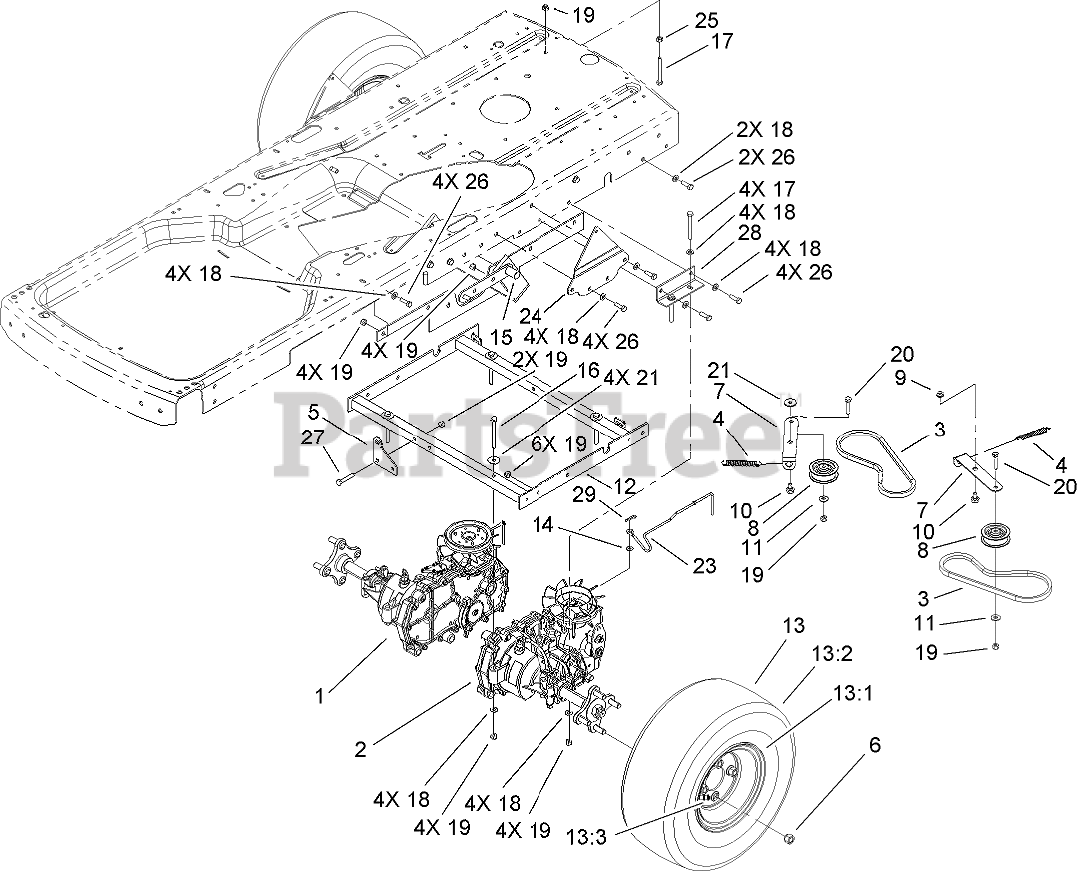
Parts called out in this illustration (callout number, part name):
1	TRANSAXLE-HYDRO, RH
2	TRANSAXLE-HYDRO, LH
3	V-BELT
4	SPRING
5	BRACKET-SPRING
6	NUT-LUG
7	ARM-IDLER
8	PULLEY-IDLER
9	NUT-HF
10	BOLT-SHOULDER
11	WASHER-FLAT
12	HYDRO FRAME ASM
13	WHEEL AND TIRE ASM
13:3	STEM-VALVE
14	WASHER-FLAT
15	BRACE-FRAME, LEFT SIDE
16	SCREW-HH
17	SCREW-HH
18	WASHER-PLAIN
19	NUT-LOCK, NI
20	SCREW-HH
21	WASHER-PIVOT
23	ARM-BYPASS, LH
24	ANCHOR-DAMPER
25	NUT-HEX
26	SCREW-HH
27	SCREW-HH
28	SUPPORT-HYDRO
29	PIN-COTTER
